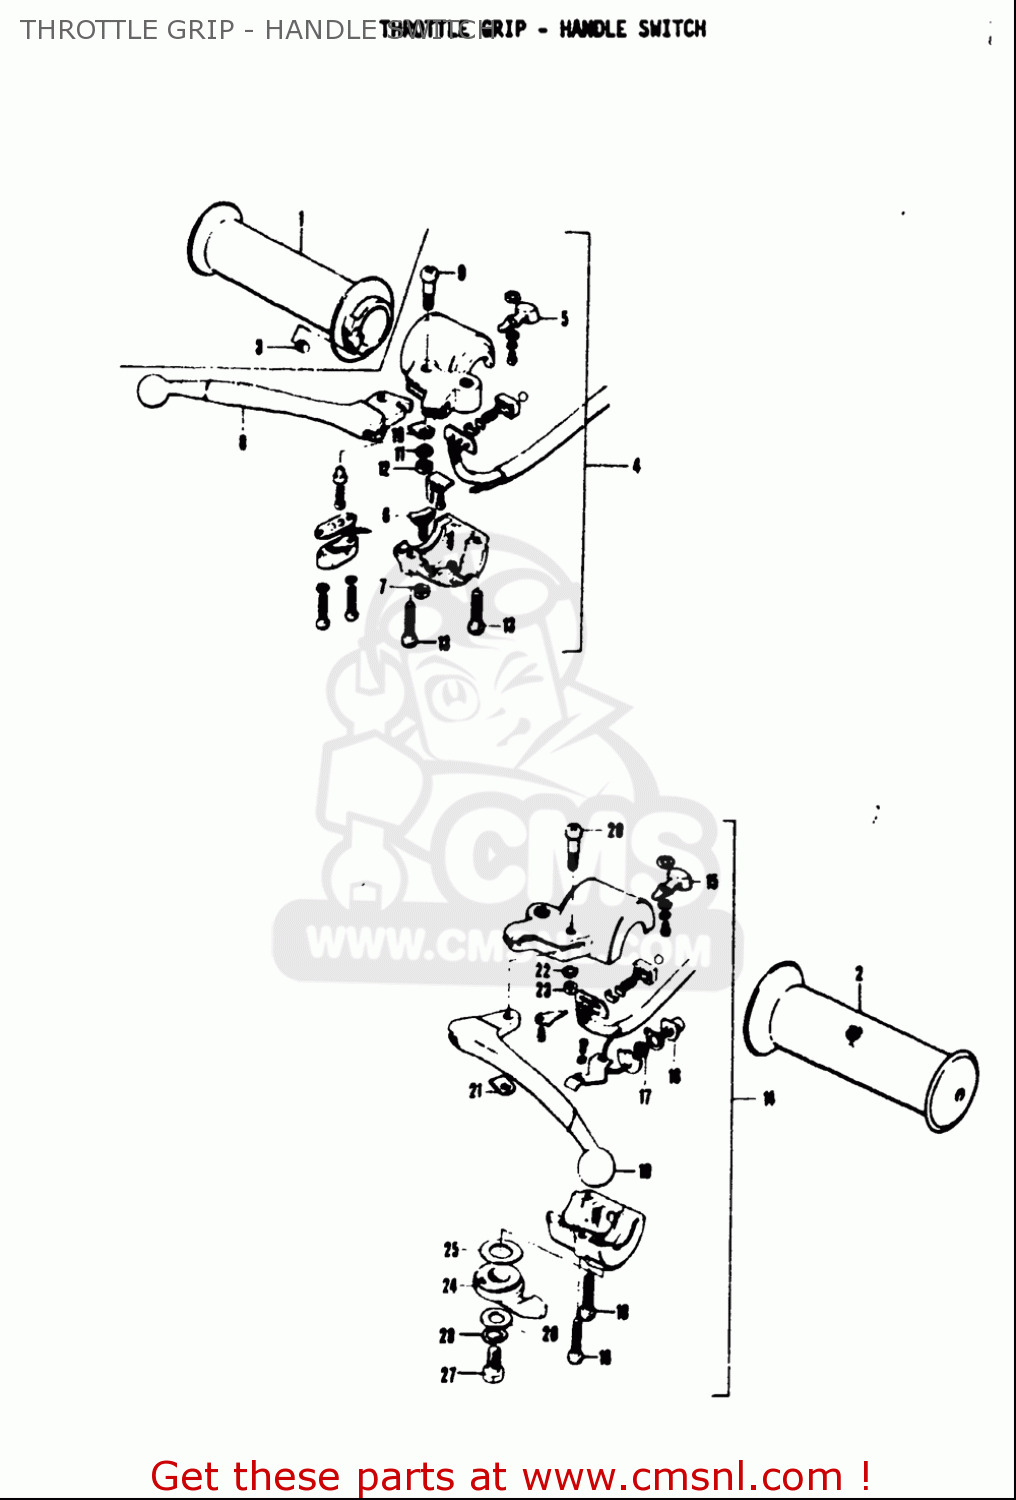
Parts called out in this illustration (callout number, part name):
1	GRIP,THROTTLE
2	GRIP
3	PIECE,THROTTLE END
7	NUT
8	LEVER,BRAKE
9	BOLT,LEVER PIVOT
10	SPACER,LEVER
11	WASHER,LOCK
12	NUT
13	SCREW
14	LEVER SWITCH ASSY,CLUTCH
16	BUTTON
17	SPRING
18	SCREW
19	LEVER,CLUTCH
20	BOLT,LEVER PIVOT
21	SPACER,LEVER
22	WASHER,LOCK
23	NUT
24	LEVER,STARTER
25	WASHER,ADJUSTER
26	WASHER(6.5X16X1)
27	BOLT
28	WASHER,LOCK
